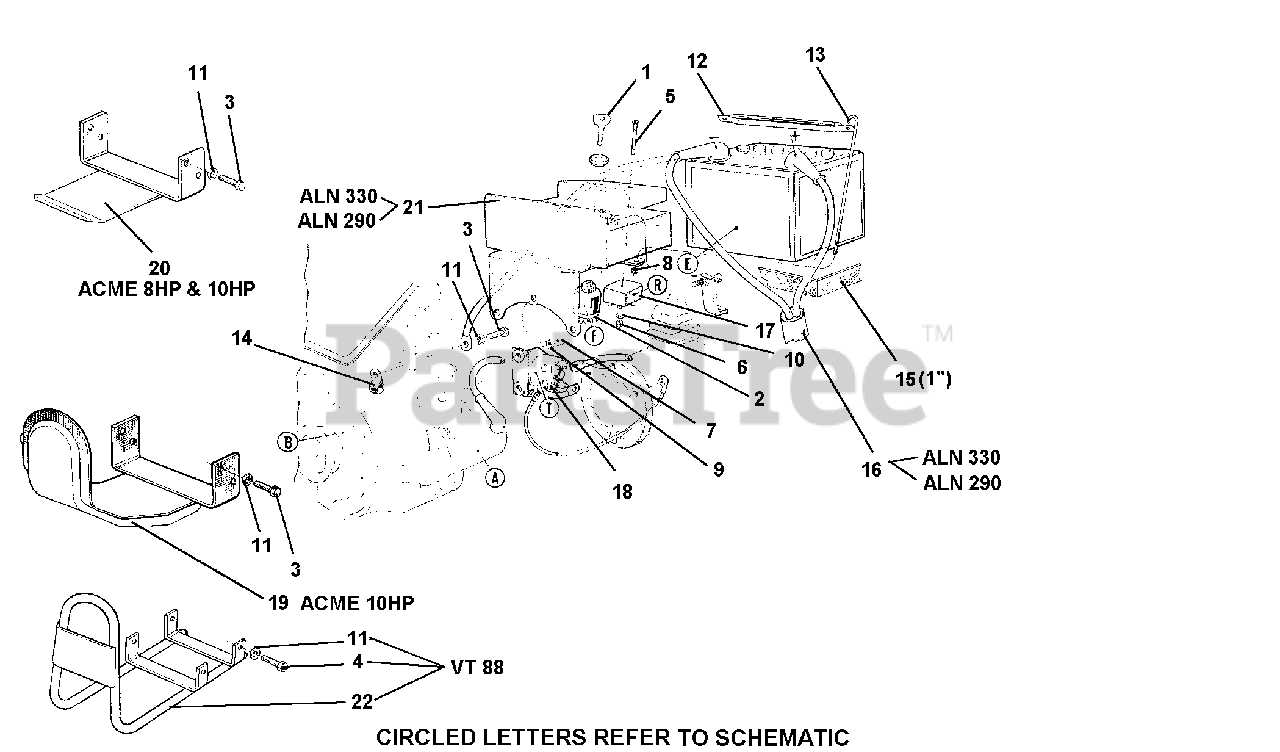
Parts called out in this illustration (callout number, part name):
3	SCREW M8 X 16
4	SCREW M8 X 20
5	SCREW TC M4 X 30 UNI 6107
8	NUT, SELF LOCKING M6
9	WASHER, FLAT 6.4
10	LOCK WASHER B 4.3
11	WASHER, LOCK 8.4
12	BATTERY BRACKET
13	BATTERY TIEROD
14	SUPPORT, ACCELERATOR CABLE
15	SHOCK-PROOF RUBBER
16	ELEC. START CABLES MC 715
18	BOSCH RELAY 0332002160
19	GUARD, MOWER MOTOR PULLEY
20	ENGINE GUARD
21	SUPPORT BATTERY
22	PULLEY GUARD
